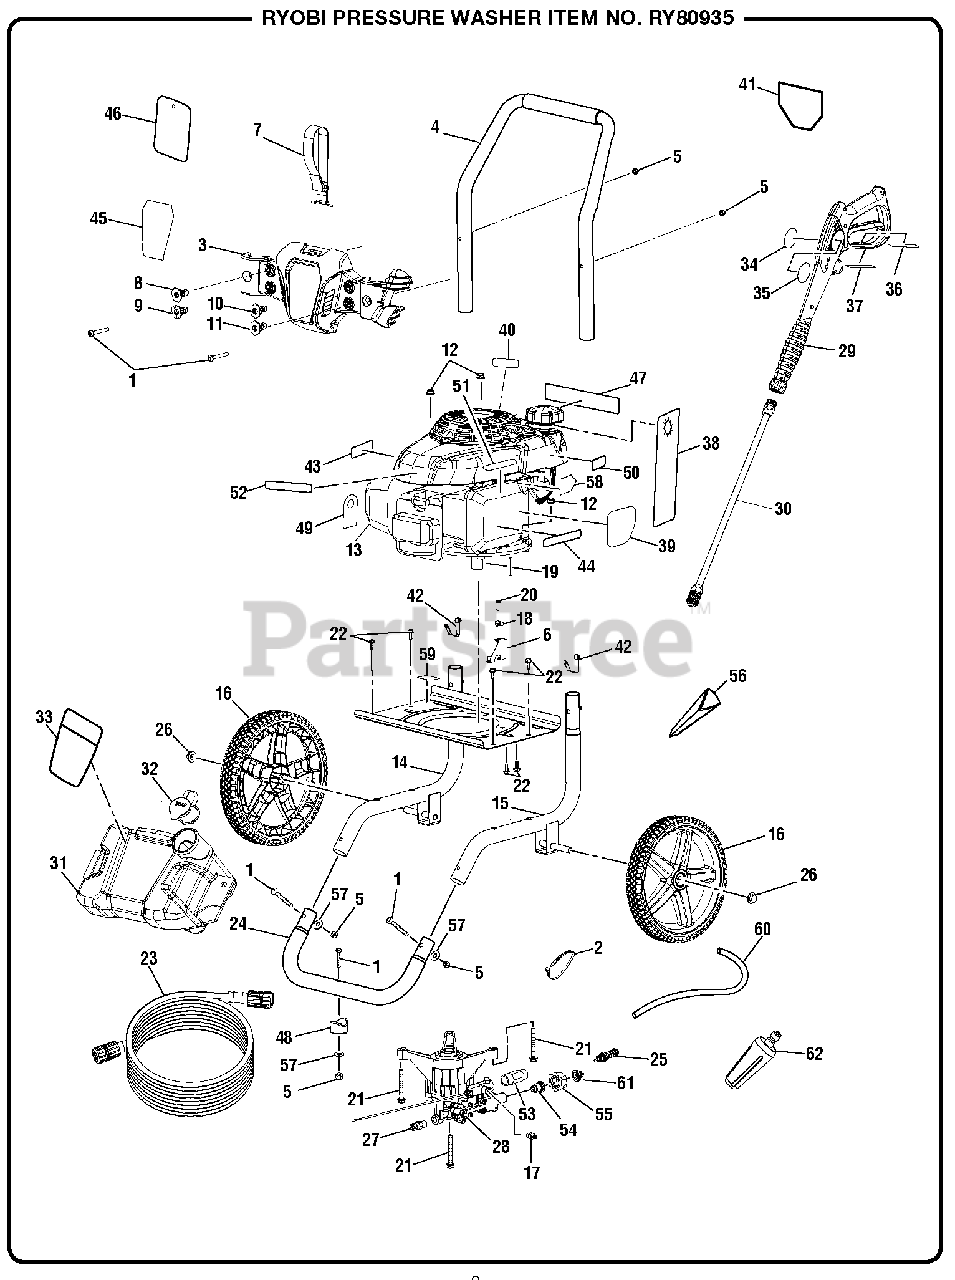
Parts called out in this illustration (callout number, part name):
1	Screw (M6 x 48 mm, T30 Torx Hd.)
3	Hose and Nozzle Holder
4	Handle w/Foam
5	Lock Nut (M6)
6	Idle Down Cable Bracket
7	Hose Holder Strap
8	40deg Nozzle
9	Soap Nozzle
10	25deg Nozzle
11	0deg Nozzle
12	Flange Nut (M8 x 1.25)
13	Engine (Honda GCV 160, 160cc OHC Vertical)
14	Main Frame Assembly (Left)
15	Main Frame Assembly (Right)
16	Wheel
17	Detergent Suction Kit
18	Idle Down Cable Clamp
19	Output Shaft Key
20	Bolt (M5 x 20 mm)
21	Bolt (M8 x 60 mm, Flange Hd.)
22	Bolt (M6 x 16 mm, Flange Hd.)
23	Hose (25 ft.)
24	Front Frame
25	Pump Unloader Valve
26	Push Cap Nut
27	Thermal Release Valve
28	Pump
29	Trigger Handle Assembly
30	Extension Wand
31	Soap Tank
32	Soap Tank Cap
33	Soap Dilution Label
34	Label (Wand Logo)
35	Label (Wand Warning)
36	Warning Label (Fr/Sp)
37	Label (Wand Rating)
38	Danger Hangtag
39	Engine Control Label
40	Combustion Label
41	Quick Start Label
42	Lock Button w/Spring Clip
43	Hot Surface Label
44	EMC Label
45	Performance Label
46	Nozzle Hangtag
47	Danger Label
49	Dipstick Hangtag
50	No E85 Label
51	Inquiries Label
52	Idle Down Label
53	Outlet Tube
57	Washer (1/4 in.)
58	Engine On/Off Label
59	Oil Fill Location Label
60	Chemical Siphon Tube
61	Filter Screen
62	Turbo Nozzle
